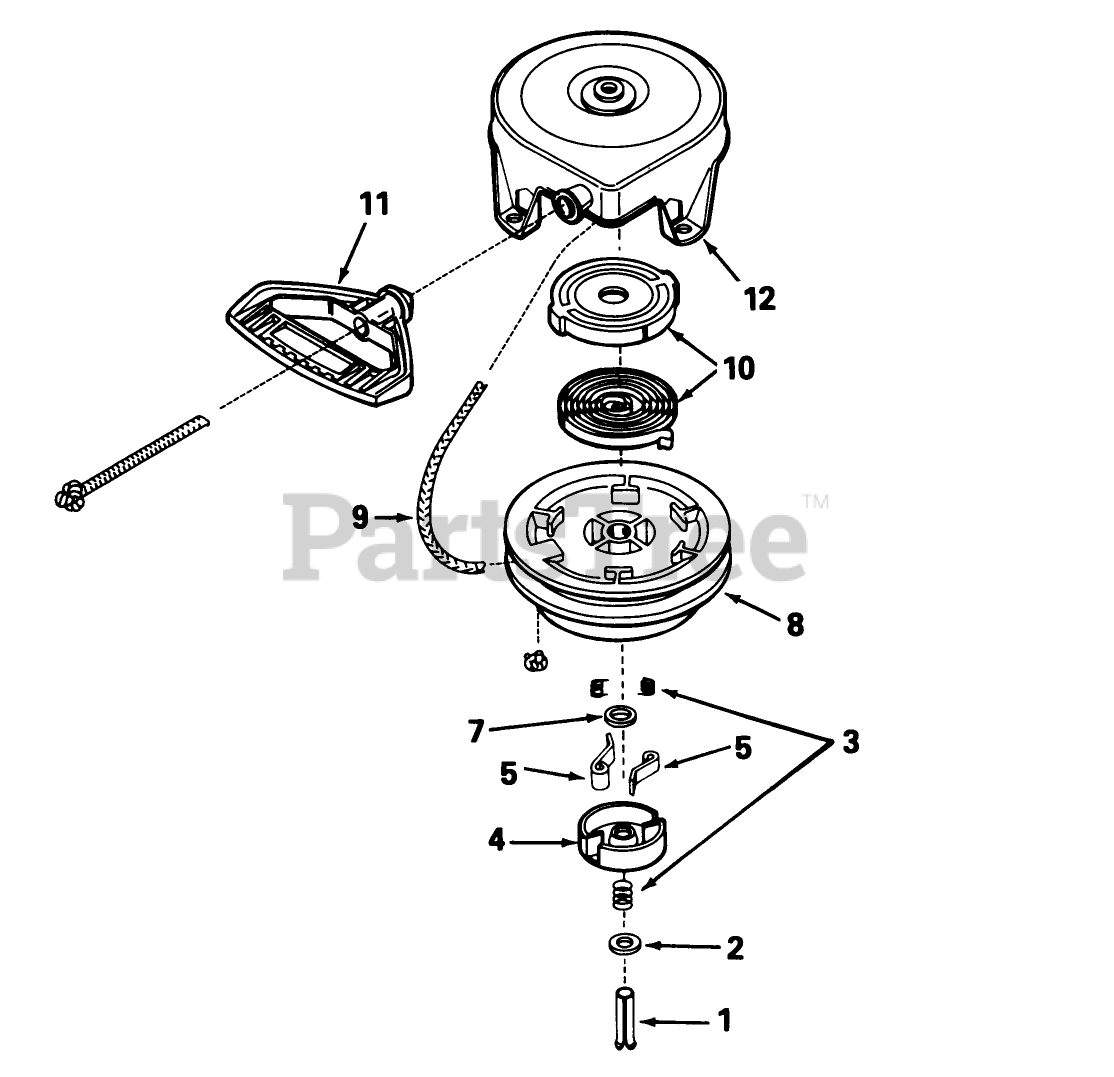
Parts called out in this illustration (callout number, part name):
1	Pin, Spring (Incl. Ref. #7)
2	Washer
3	Spring Assembly
4	Retainer
5	Dog-Starter
7	Washer
8	Pulley
9	Rope-Starter
10	Spring Keeper Assy.
11	Handle-Starter, Mitten Grip
12	Housing Assy., Starter
